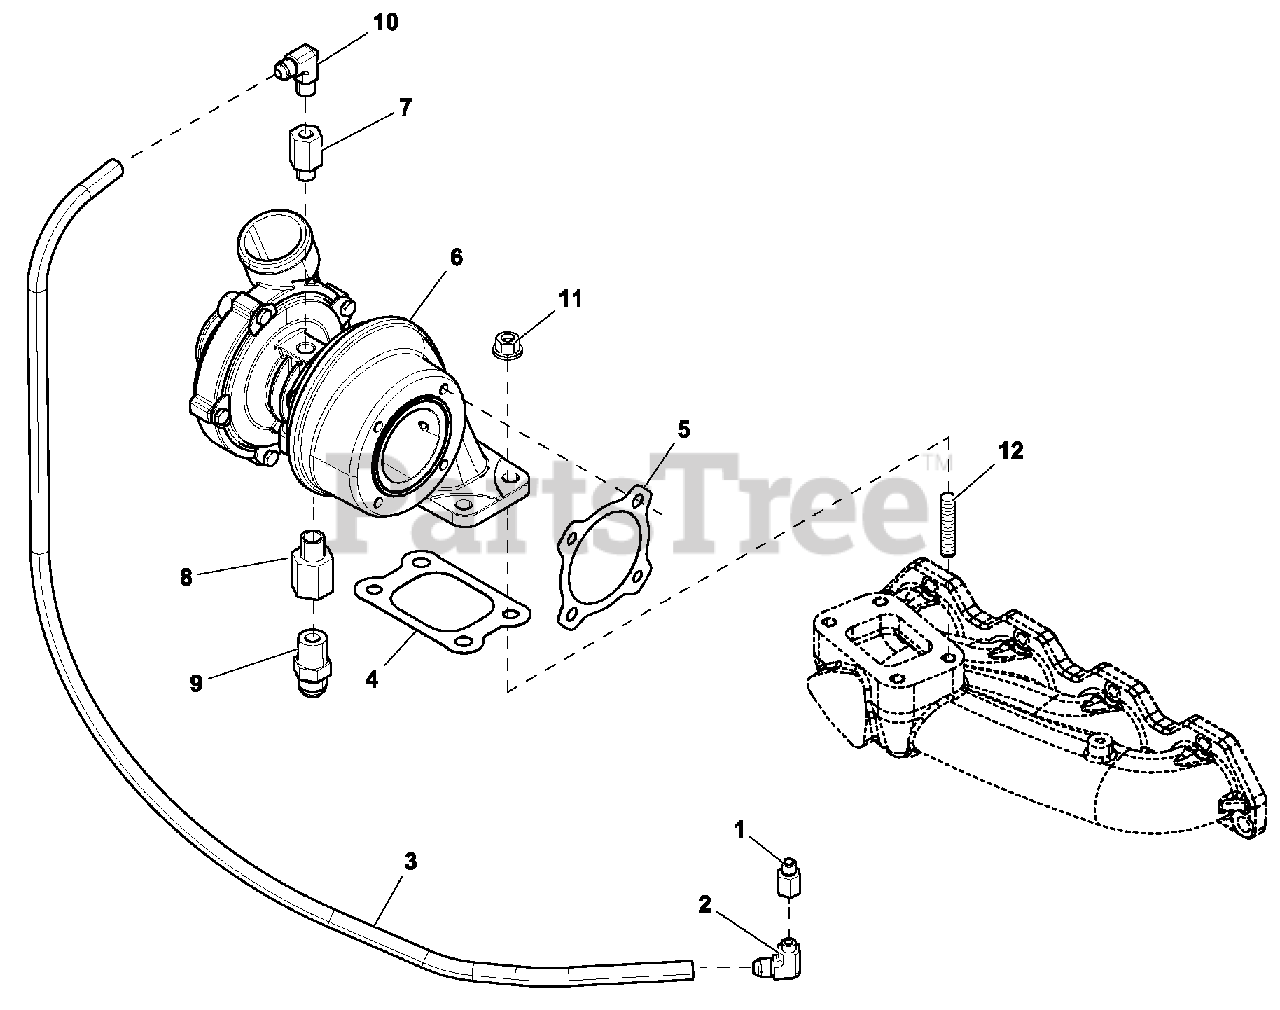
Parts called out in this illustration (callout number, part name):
1	ADAPTER 1/8NPTF TO 1/8 BSPT
2	MALE ELBOW 45 #49X3
3	OIL SUPPLY 3LHA(38")
4	GASKET 2.4L G2
5	GASKET 2.4L G2
6	TURBOCHARGERG2 2.4L
7	ADAPTER 1/4NPT X M12-1.5
8	ADAPTER 1/2NPT X M16-1.5
9	ADAPTER 1/2 NPTX 37JIC 3/4-16
10	ADAPTER 90D JIC37 1/4NPT X 1/2
11	NUT H EX FL WHIZ M10-1.50
12	STUD M10-1.5 X 40 G10.9
